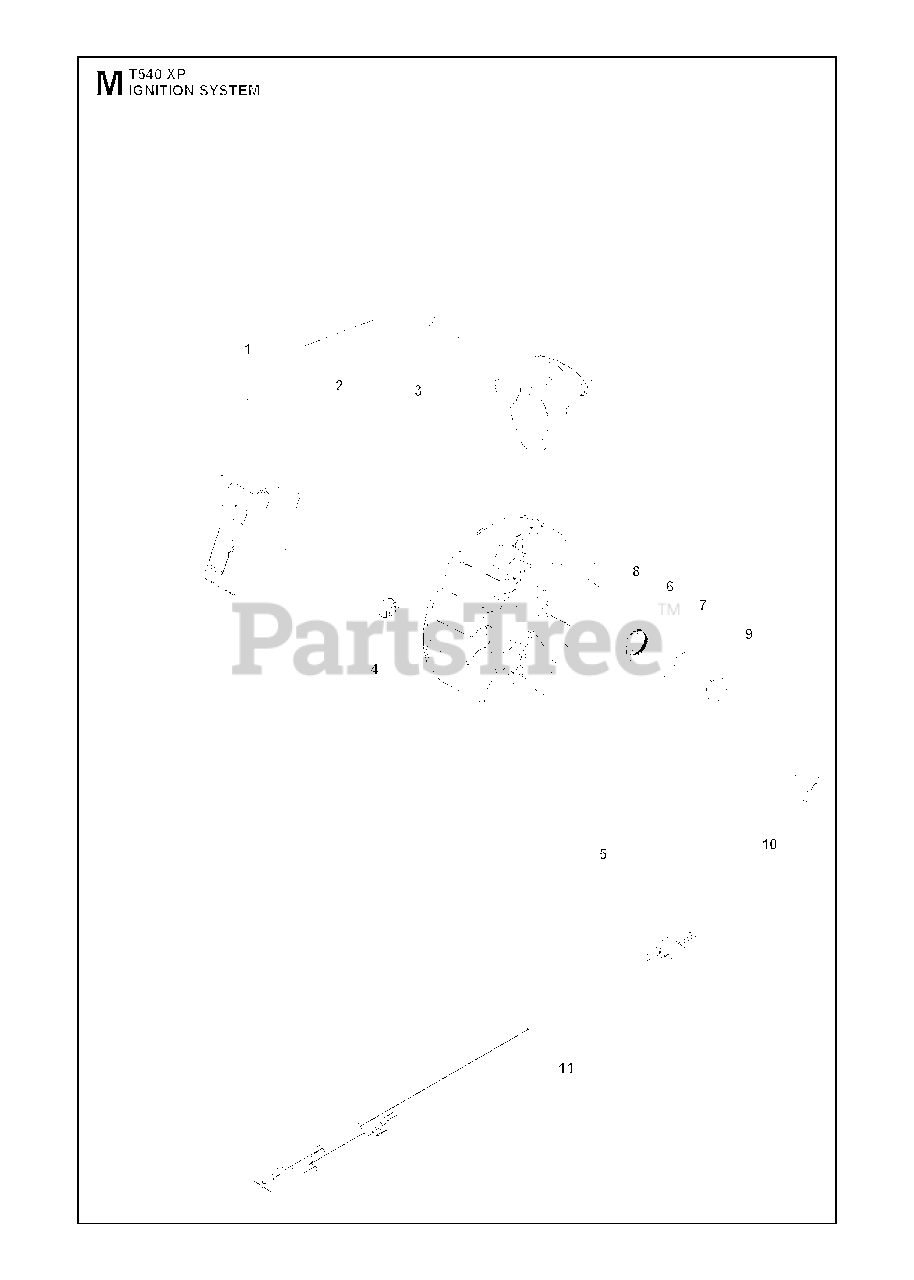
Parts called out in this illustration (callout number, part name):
1	IGNITION MODULE
2	SPARK PLUG CAP ASSY
3	SPRING
4	SCREW ITXSCFM
5	FLYWHEEL ASSY
6	SPRING
7	PAWL
8	WASHER
9	SCREW
10	NUT W/ WASHER
11	WIRING ASSY
